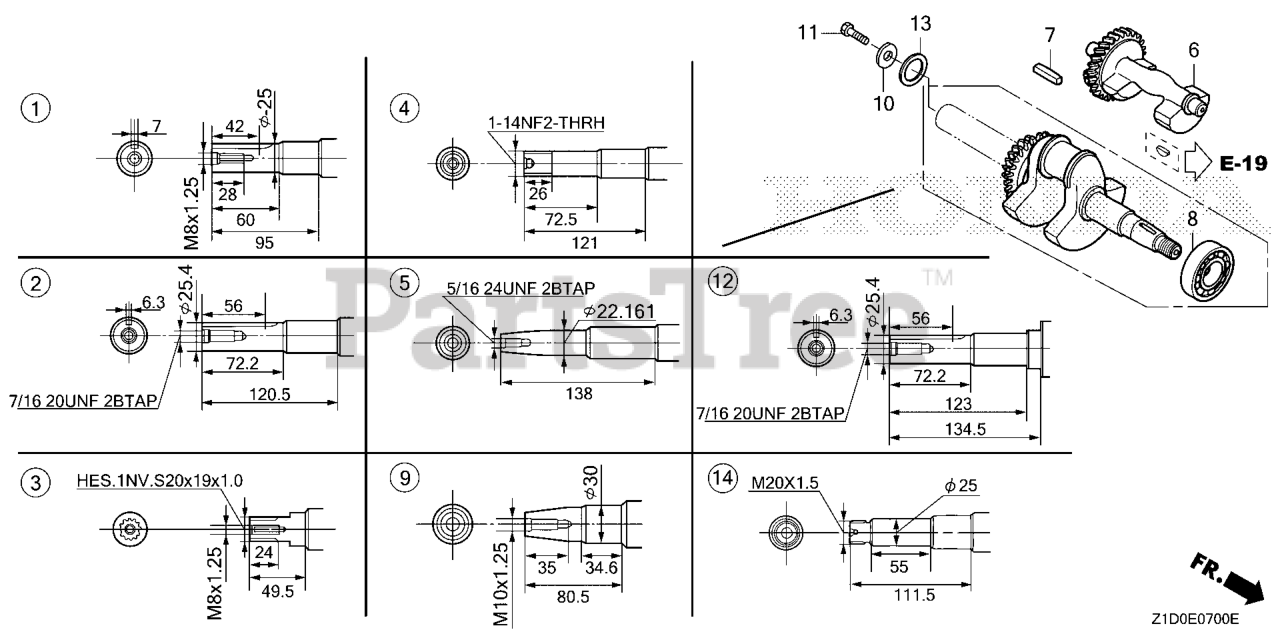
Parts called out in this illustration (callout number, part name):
7	KEY (6.3X6.3X43)
8	BEARING, RADIAL BALL (6206 SH)
12	CRANKSHAFT (Q-TYPE)
13	WASHER, THRUST (30MM) (NOT AVAILABLE)
